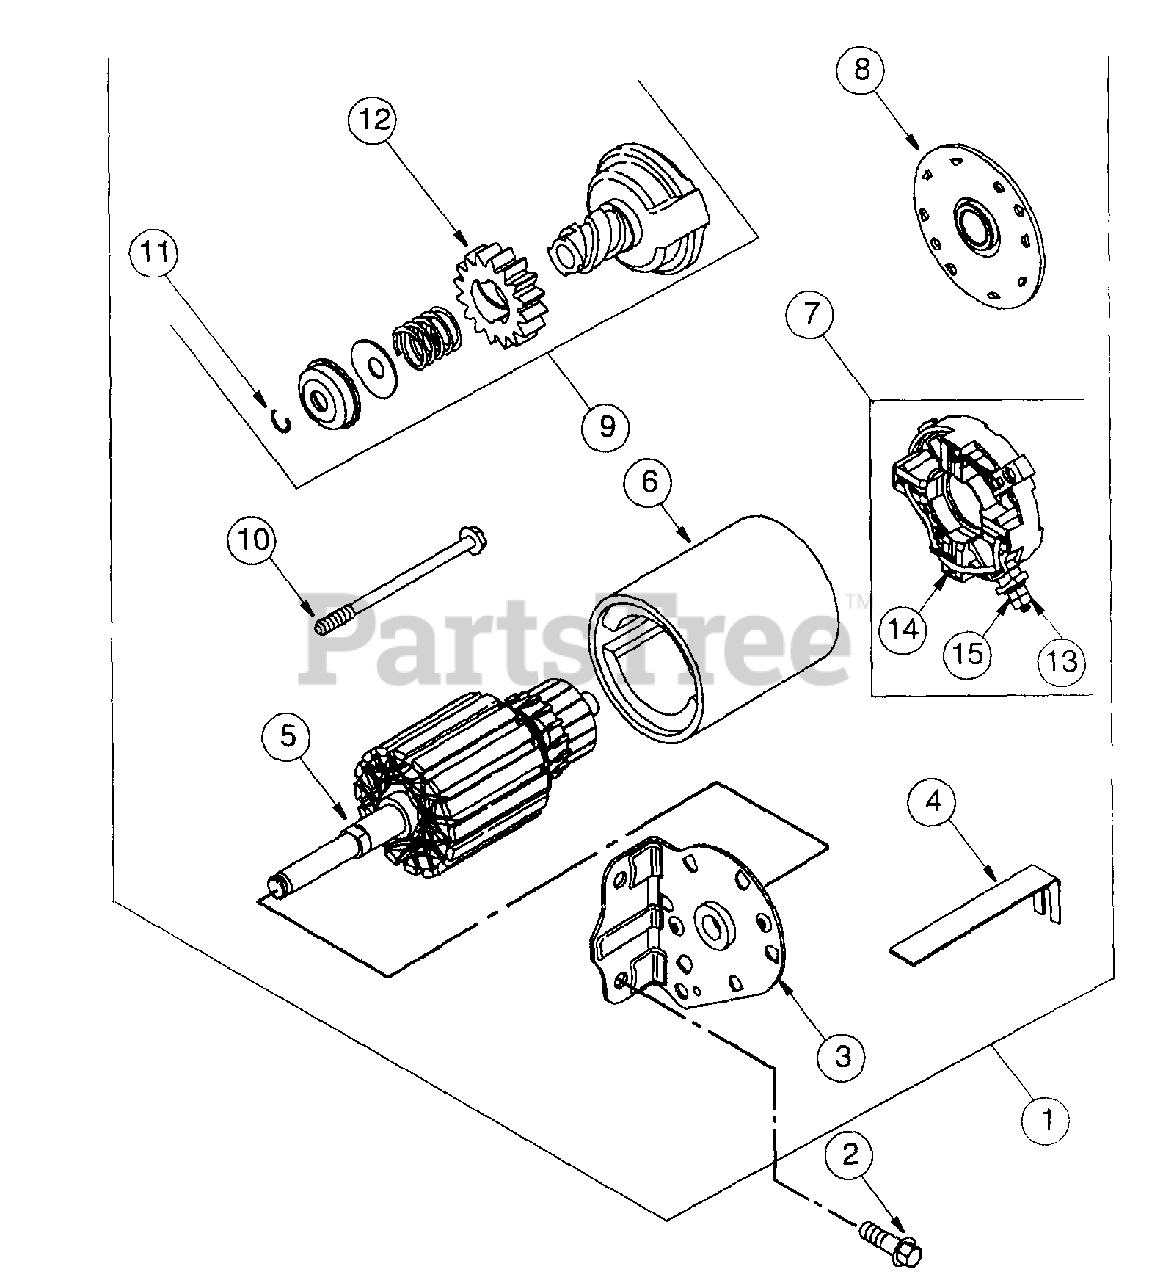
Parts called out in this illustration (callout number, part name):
1	Starter Motor Assembly
2	Screw, Hex
3	Drive End Cap Assembly
4	Strap, Starter
5	Armature Assembly
6	Housing Assembly
7	Retainer, Brush
8	End Cap Assembly, Commutator
9	Starter Drive Group
10	Screw, Hex
11	Ring, Retaining
12	Gear, Starter
13	Nut, Hex
15	Washer, Flat
